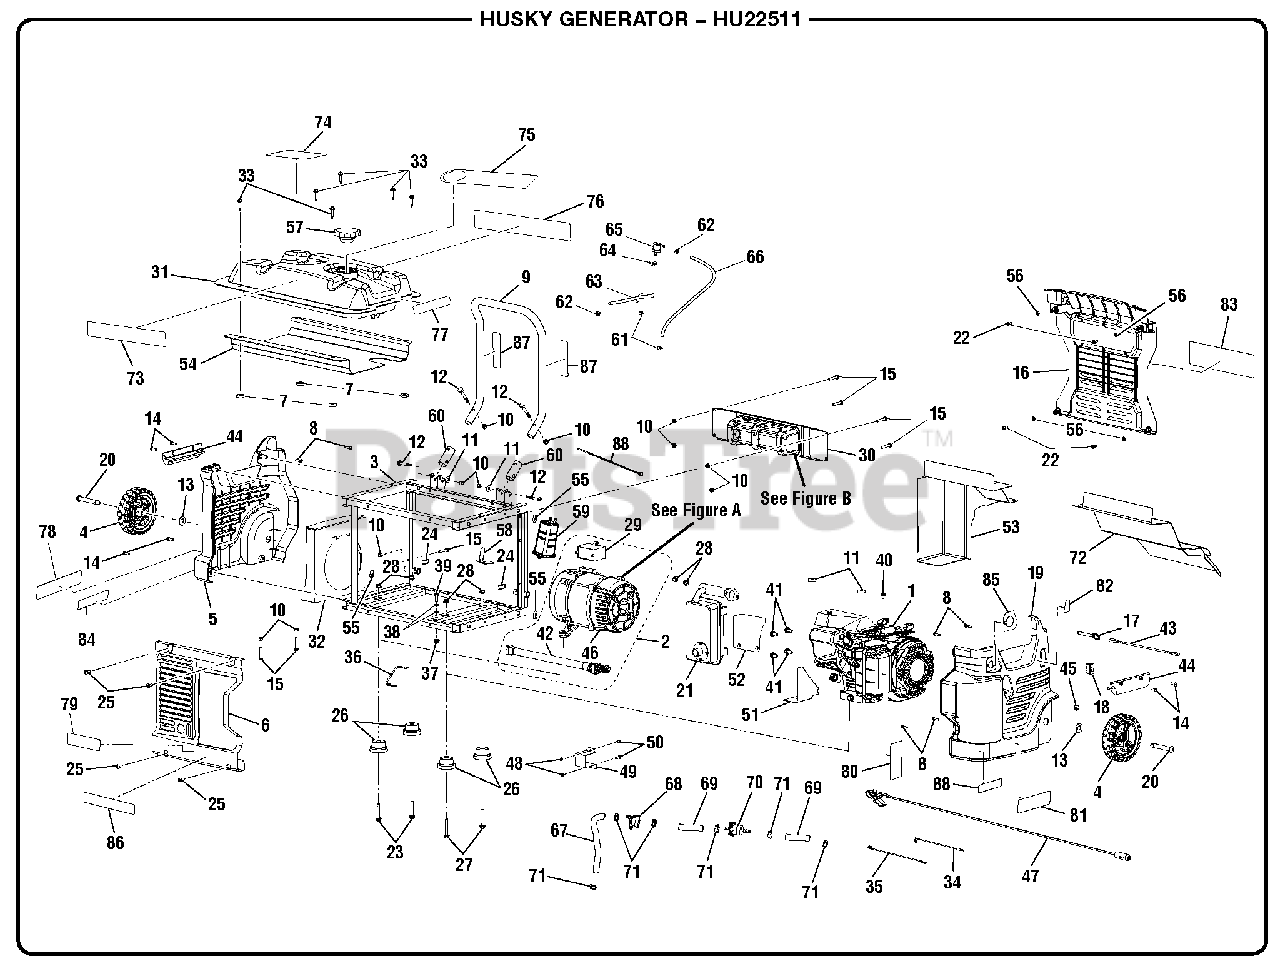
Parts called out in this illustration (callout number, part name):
2	Generator Head w/Capacitor
3	Frame Assembly
5	Panel Cover
6	Service Panel
7	Nylon Washer (D20 x D8 x 4.5t)
8	Screw (#9-18 x 20 mm)
9	Handle Assembly
10	Lock Nut (1/4-20 in.)
11	Washer (1/4 in.)
12	Bolt (1/4-20 x 2 in., Hex Hd.)
13	Washer (1/2 in.)
14	Screw (12-14 x 15 mm)
15	Screw (1/4-20 x 1-3/4 in., T30 Torx Hd.)
16	Control Panel Cover
17	Release Pin
19	Outer Panel
20	Wheel Axle
21	Muffler Assembly
22	Screw (#9-18 x 15 mm)
23	Bolt (M8 x 45 mm, Flange Hd.)
24	Axle Clip
25	Screw (1/4-20 x 1/2 in.)
26	Rubber Foot
27	Bolt (M8 x 50 mm)
28	Lock Nut (M8)
29	Capacitor
30	Control Panel Assembly
31	Fuel Tank Assembly [(Metal) Inc. Key No. 57]
32	Intake Heat Shield
33	Screw (#10-16 x 1 in.)
34	White Assembly Wire (18 Ga)
35	Brown Wire Assemly (18 Ga)
36	Ground Assembly Wire
37	Flange Nut (15/16-18)
38	Washer (5/16 in., Star)
39	Bolt (5/16-18 x 3/4 in.)
40	Bolt (M6 x 10 mm)
41	Bolt (5/16-24 x 5/8 in.)
42	Pigtail (Male Connector w/ Wire)
43	Lanyard (3/16 in.)
44	Handle Grip
45	Recoil Rope Guide
46	Generator Head Assembly
47	Battery Cable Assembly
48	Hex Nut (M5)
49	Capacitor Holder
50	Bolt (M5 x 16 mm, Pan Hd.)
51	Heat Shield (Engine Air Inlet)
52	Heat Shield (Separator)
53	Heat Shield (Surround Muffler)
54	Heat Shield (Under Fuel Tank)
57	Fuel Tank Cap
58	Canister Bracket
61	Fuel Line Clamp (3/8 in.)
62	Fuel Line Clamp (5/16 in.)
63	Fuel Line Hose (4 mm, 305 mm)
65	Fuel Check Valve
66	Fuel Line Hose (5 mm, 432 mm)
67	Fuel Hose (150 mm)
68	Fuel Shut-off Valve
69	Fuel Hose (100 mm)
70	Fuel Line Filter
71	Fuel Line Clamp (1/2 in.)
72	Heat Shield
73	Do Not Stand Label
74	CPSC Label
75	Engine Warning Hangtag
76	Danger Label
77	Fire Danger Label
78	Ground Warning Label
79	Hot Surface Label
80	Starting Instructions Label
81	Data Plate
82	Engine Switch Label
83	Logo Label
84	Combustion Label
85	Fuel Valve Label
86	Engine Lubricant Label
87	Hot Handle Warning Label
88	Cable Tie (18.6 in.)
